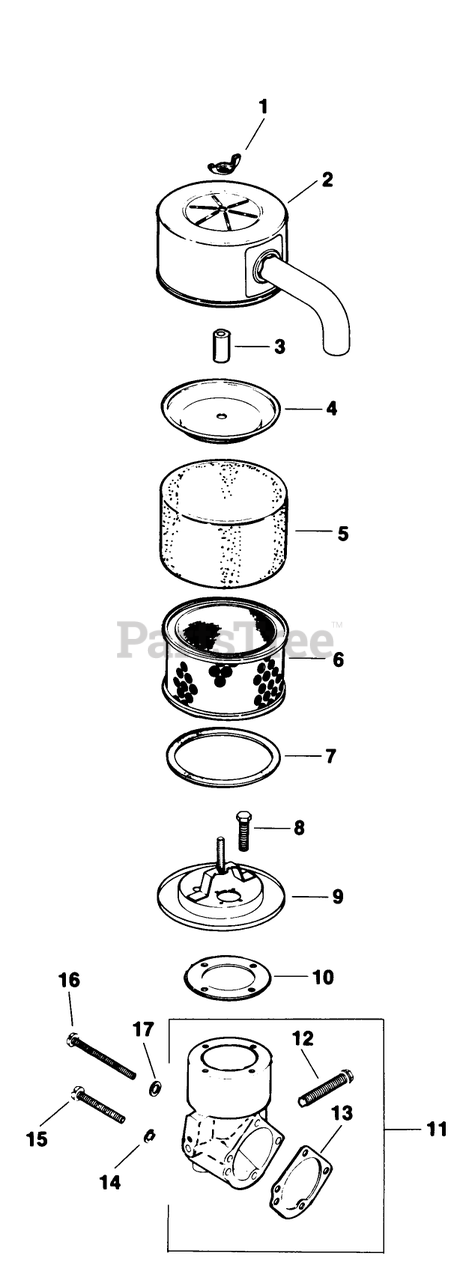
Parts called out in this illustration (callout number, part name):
1	Nut-Wing
2	Cover-Air Cleaner
3	Seal
4	Cover-Inner
5	Element
6	Element
7	Seal
8	Screw-H.C.
9	Base-Air Cleaner
10	Gasket-Air Cleaner
11	Kit-Elbow (Incl. Ref. #12 & 13)
12	Screw-H.C
13	Gasket-Elbow
14	Washer
15	Screw-R.H.M.
16	Screw-R.H.M.
17	Washer
